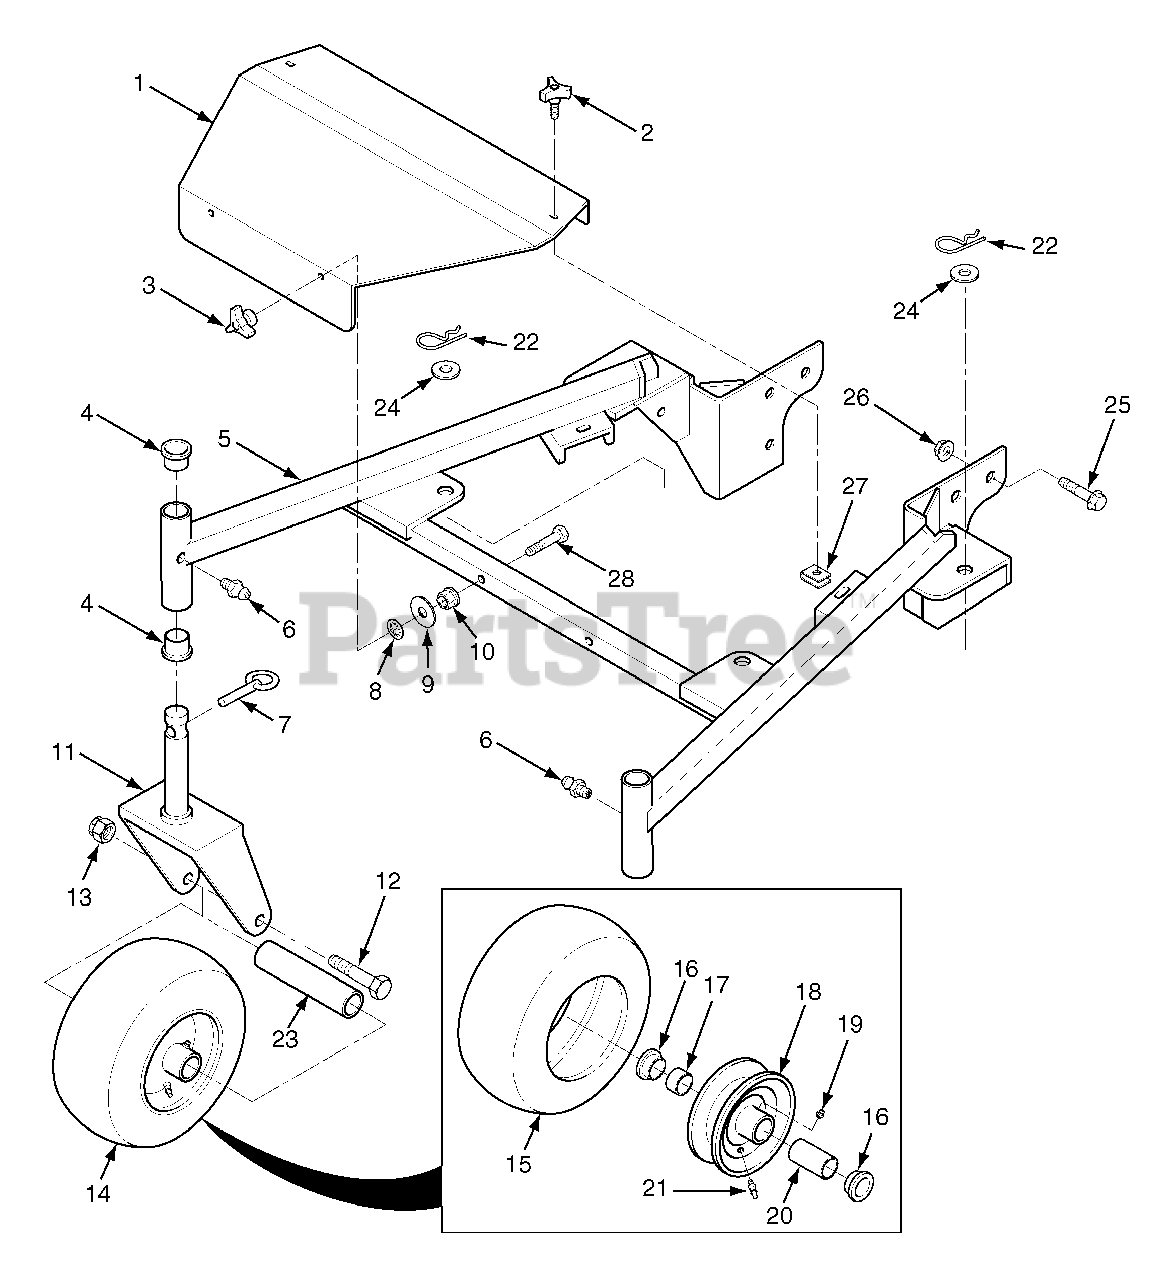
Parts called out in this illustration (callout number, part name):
1	48" Belt Cover With Decal
2	Knob With Stud
3	Knob, Deck Cover Mounting
4	Bushing, Caster
5	Frame Weldment, Deck Mounting - 48"
6	Grease Fitting Str. 1/4-28 Self Tap
7	Quick Pin, .438" Dia.
8	Nut, Push-On - 3/8" Dia.
9	Flatwasher, 3/8" (.391 x .938 x .105)
10	Nut, 3/8-16 Serrated Flange Hex Head
11	Yoke, Caster Wheel
12	Capscrew, Hex Head 1/2-13 x 6-1/2"
13	Locknut, 1/2-13 Elastic Stop
14	Wheel Assembly, Caster
15	Tire, 11 x 4.00-5
16	Retainer
17	Roller Bearing
18	Rim, 5" x 2-3/4"
19	Grease Fitting Str.1/4-28
20	Roller Bearing .625 x 3.25"
21	Tire Valve, Purchase Locally
22	Hair Pin Cotter, .177 x 3-1/4"
23	Sleeve, Caster Wheel
24	Flatwasher, 5/8" - (.688 x 1.75 x .134)
25	Capscrew, 1/2-13 x 1" Serrated Flange Hex Head
26	Nut, 1/2-13 Spiralock
27	U-Nut, 3/8-16
28	Capscrew, Hex Head 3/8-16 x 2-1/4"
